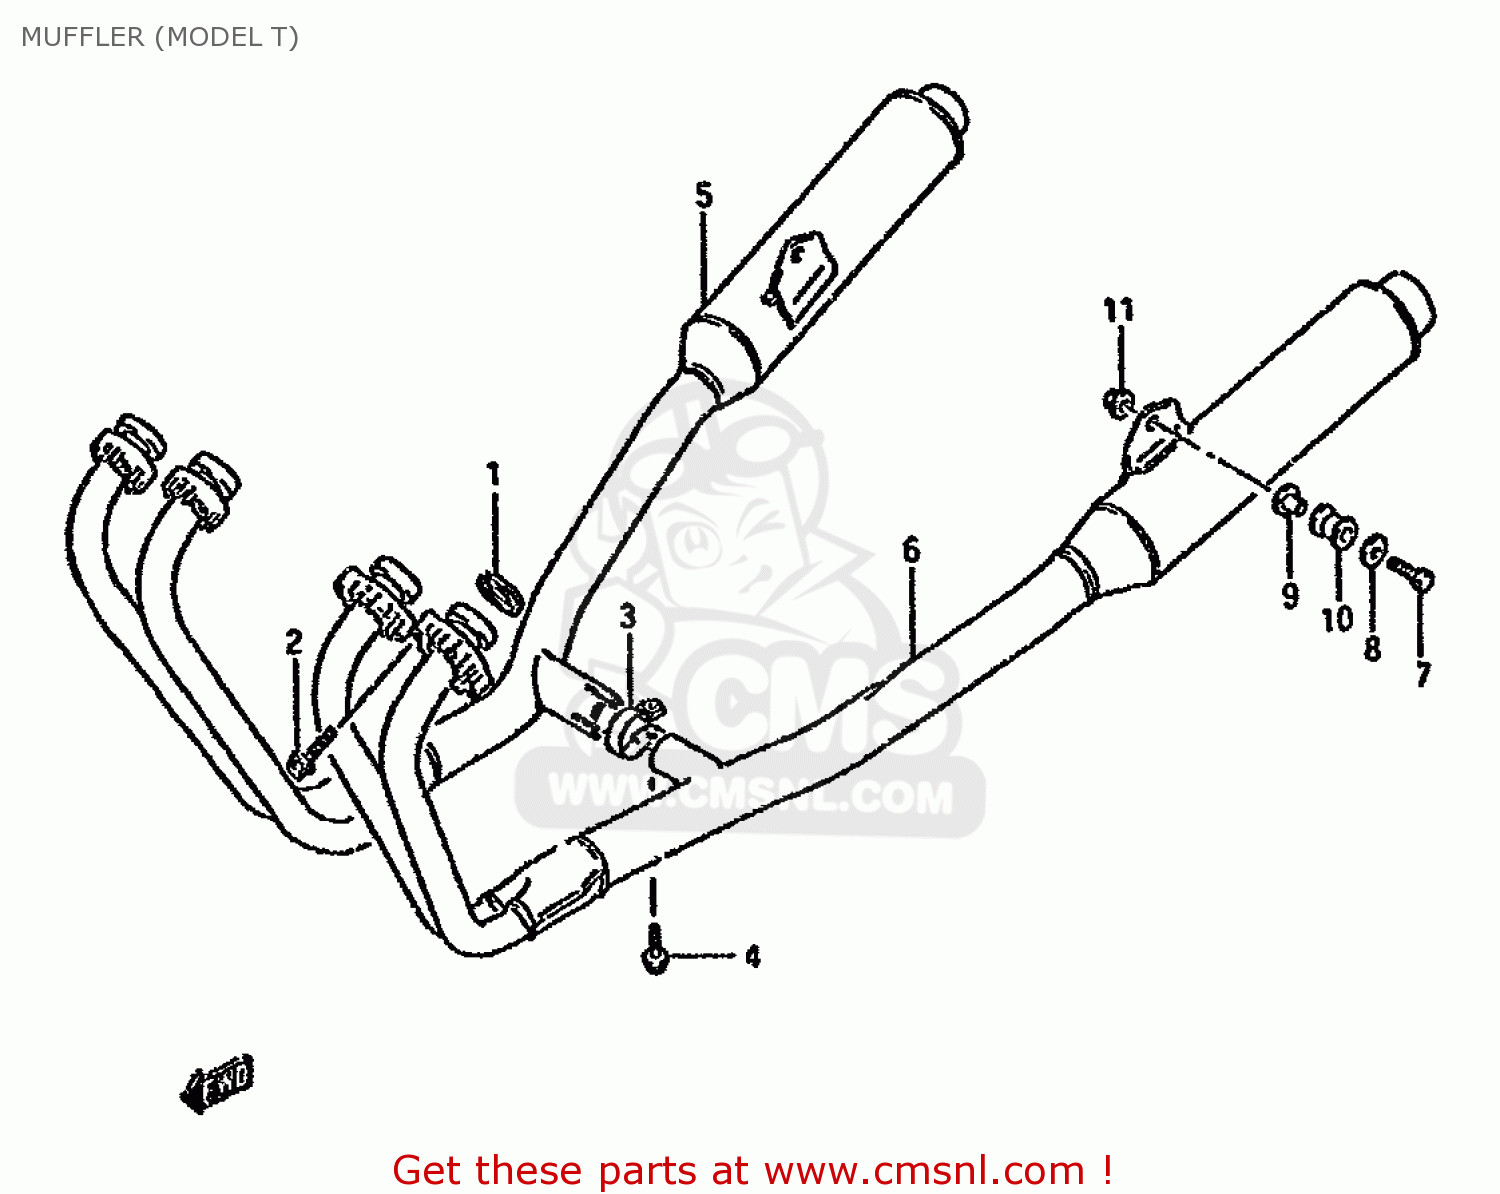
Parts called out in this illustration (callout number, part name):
1	GASKET,EXHAUST (NAS)
2	BOLT
3	CLAMP,MUFFLER CONNECTOR
4	BOLT
5	MUFFLER ASSY,RH
6	MUFFLER ASSY,LH
7	BOLT
8	WASHER (8.1X33X1.6)
9	SPACER(8.6X12X27.1)
10	CUSHION
11	NUT
